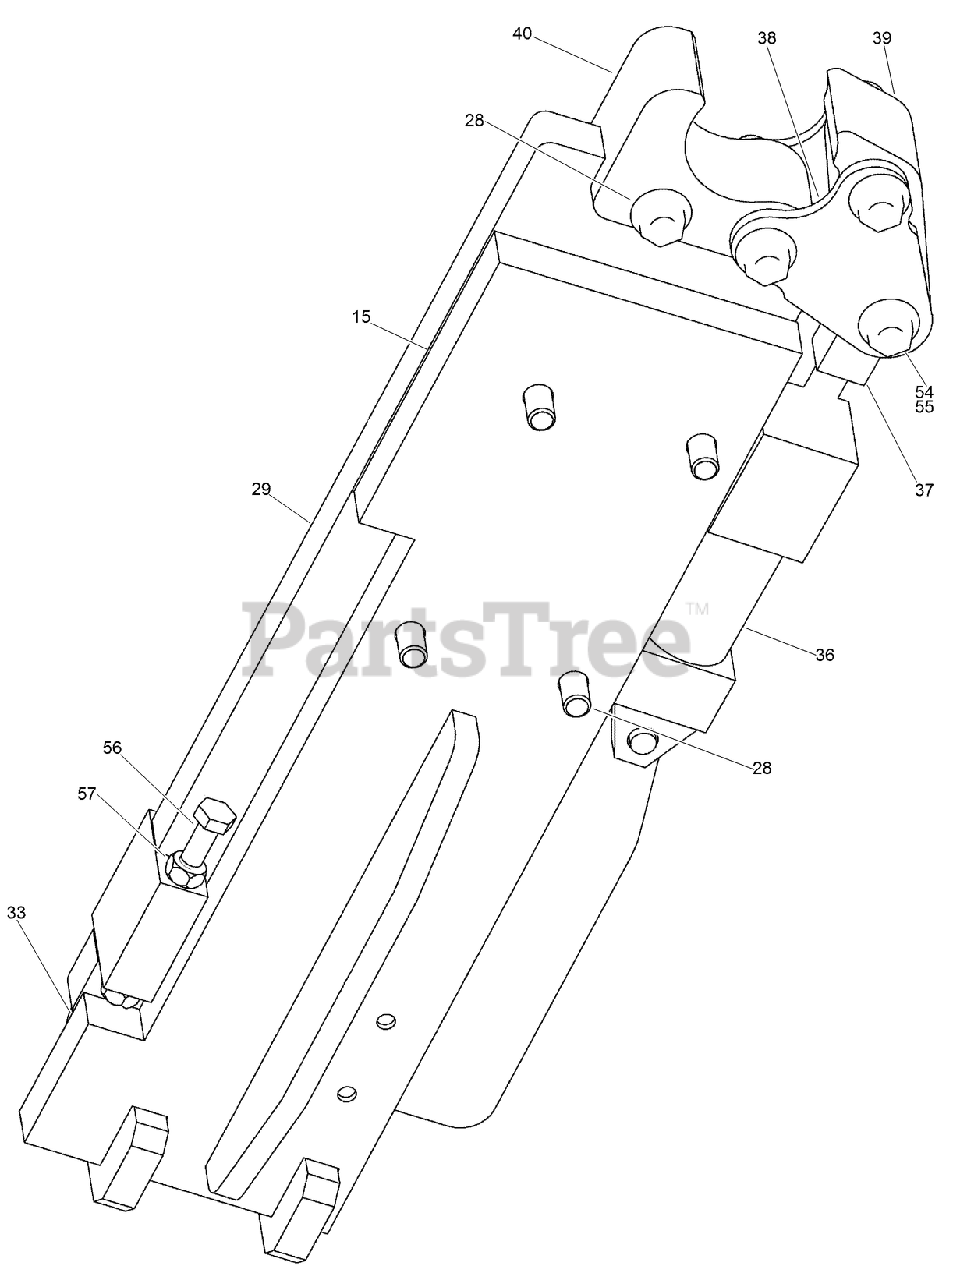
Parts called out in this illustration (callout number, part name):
15	ASSEMBLY - Spacer
28	SCREW, METRIC FLANGE w/BODY - M10 x 60
29	ASSEMBLY - Slider Extension
33	PIN - Clevis
36	CYLINDER - Hydraulic
37	ROD-EYE, CYLINDER
38	PLATE-GRIPPER, ROTATE
39	INSERT-GRIPPER, ROTATE
40	INSERT-GRIPPER, FIXED
54	SCREW-HHF
55	NUT-FLANGE, NYLOCK
56	SCREW-HH
57	NUT - M8 Class 10 ZND
